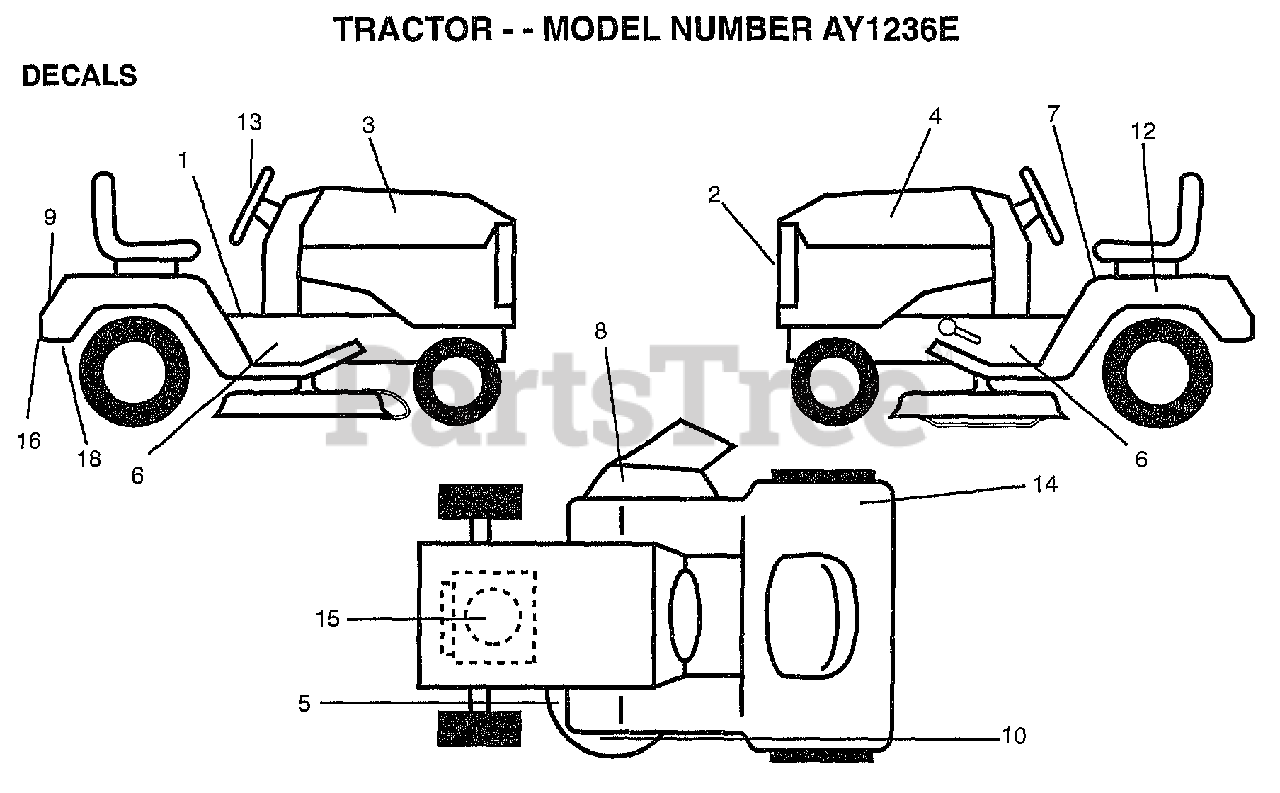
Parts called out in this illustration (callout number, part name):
1	DECAL CLUTCH/BRAK
2	"DECAL,LIGHT BOX"
3	DECAL.HOOD.RH
4	DECAL.HOOD.LH
5	DECAL.V.BELT
6	"DECAL CHASSIS,HOT"
7	DECAL.READ.O.MANU
8	DECAL.DANGER.CUTF
9	DECAL.FENDER
10	DECAL DECK WIZ +
12	DECAL.BATRY.3-3908
13	DECAL.INSERT.STR
16	DECAL.DRAWBAR.LDL
18	DECAL.EURO.ST.CE.
